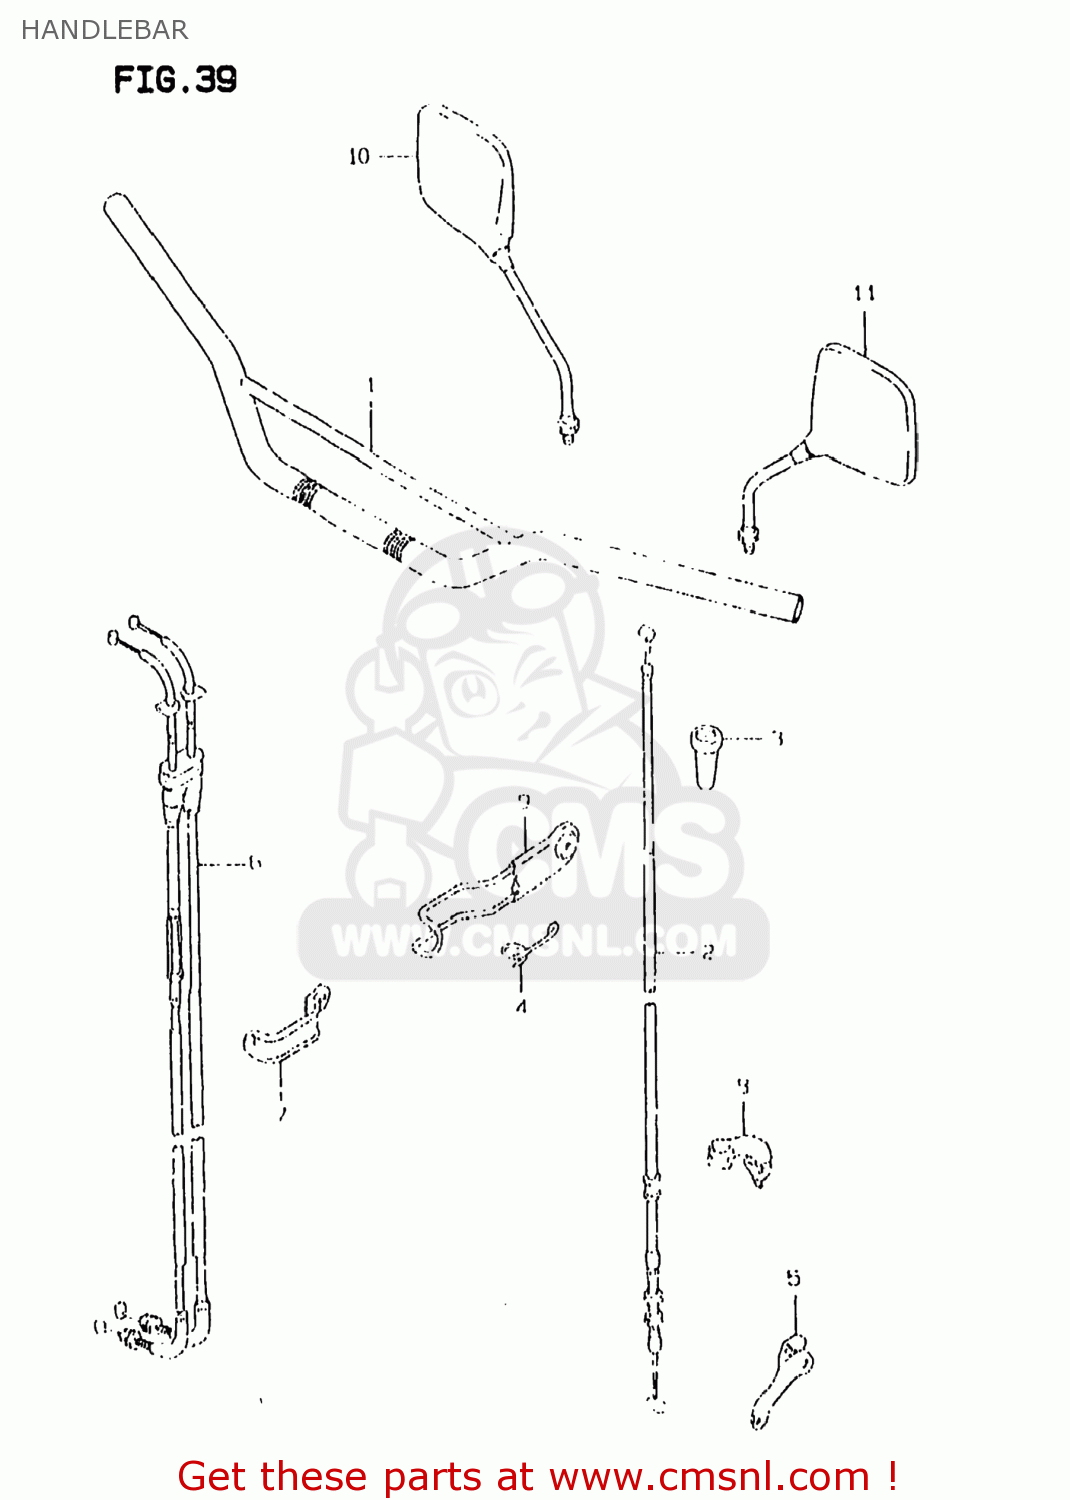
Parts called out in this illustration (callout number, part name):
1	HANDLEBAR
2	CABLE ASSY,CLUTCH
3	BOOT,CLUTCH CABLE
4	GUIDE,CLUTCH CABLE
5	STOPPER,CLUTCH CABLE
6	CABLE ASSY,THROTTLE
7	CLAMP
8	CLAMP,CLUTCH CABLE
9	GUIDE,CLUTCH CABLE
10	MIRROR ASSEMBLY,RIGHT
11	MIRROR ASSEMBLY,LEFT
